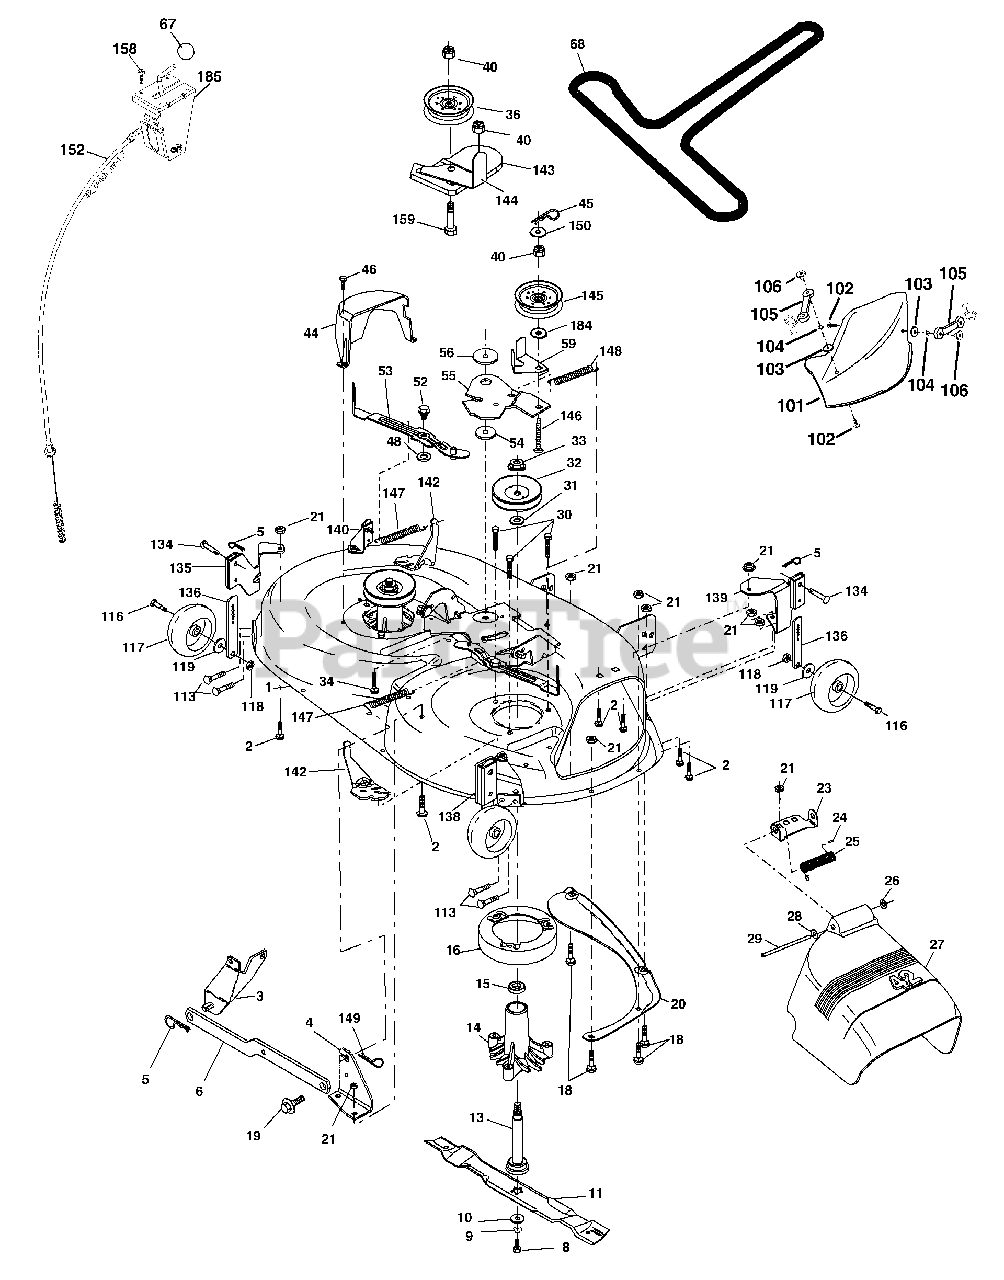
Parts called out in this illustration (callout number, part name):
1	Mower Deck Assembly, 42"
2	Bolt
3	Bracket Asm Fr. Sway Bar 3/42
4	Bracket Asm Deck 42" Sway Bar
5	Retainer Spring
6	Bar Sway Deck
8	Bolt 3/8-24 x 25 Gr. 8 patched
9	Washer, Lock
10	Washer, Hardened
11	Blade, Mulching 42" Std
11	Blade Mower 42" Hi-Lift
11	Blade Mulching 42" Premium
13	Shaft Assembly, Mandrel, Vented
14	Housing, Mandrel, Vented
15	Bearing, Ball, Mandrel
16	Stripper, Mandrel Deck
18	Bolt, Carriage 5/16-18 x 5/8
19	Bolt, Shoulder
20	Baffle, Vortex
21	Nut
23	Bracket, Deflector Mower 42"
24	Cap, Sleeve 80 x 112 Blk Mower
25	Spring, Torsion, Deflector 2 52
26	Nut, Push Phos & Oil
27	Shield, Deflector 42" Blk
28	Washer 11/32 x 5/8 x 16 Ga.
29	Rod, Hinge 42" 6 75 W/G
30	Screw Thdrol Washer Head
31	Washer, Spacer
32	Pulley, Mandrel
33	Nut, Toplock 9/16 Flange
34	Bolt Carr Sh 3/8-16 x 1-1/2 Gr. 5
36	Pulley, Idler, Flat
44	Guard, Mandrel, LH
45	Retainer
46	Screw, Thdrol 1/4-20 x 5/8 T
48	Washer, Hardened
52	Bolt, Shoulder 5/16-18 unc
53	Arm Assembly, Pad, Brake
54	Washer, Hardened
55	Arm, Idler
56	Spacer, Retainer
59	Guard TUV Idler
67	Knob
68	V-Belt, 42" Mower
101	Mulcher Cover
102	Screw Pin Hd Phillips 10-24 x 5/8
103	Washer #10
104	Washer Lock #10
105	Latch Assembly, Bagger
106	Nut, Weld
113	Screw 5/16-18 x 3/4
116	Bolt, Shoulder
117	Wheel, Gauge
118	Nut Centerlock 3/8-16
119	Washer 3/8 x 7/8 x 14 Ga.
134	Pin Head Rivet
135	Bracket Asm. Whl. Ga. Rear LH
136	Bar Adjusting Ga. Whl.
138	Bracket Asm. Whl. Ga. Rear RH
139	Bracket Asm. Whl. Ga. Front RH
140	Bracket Asm. Whl. Ga. Front LH
142	Arm Spring Brake Mower
143	Bracket Arm Idler 42"
144	Keeper Belt 42" Clutch Cable
145	Pulley Idler Flat
146	Bolt Carriage Idler
147	Spring Extension
148	Spring Return Idler
149	Retainer Spring Yellow
150	Washer 9/32 x 3/4 x 16 Ga.
152	Clutch Cable 42"
158	Screw Hex Thd Cut 1/4-20 x 5/8
159	Bolt Rdhd Sqn 3/8-16 unc x 1-3/4
184	Washer 13/32 x 7/8 x 10 Ga.
185	Head Asm. Cable Clutch
